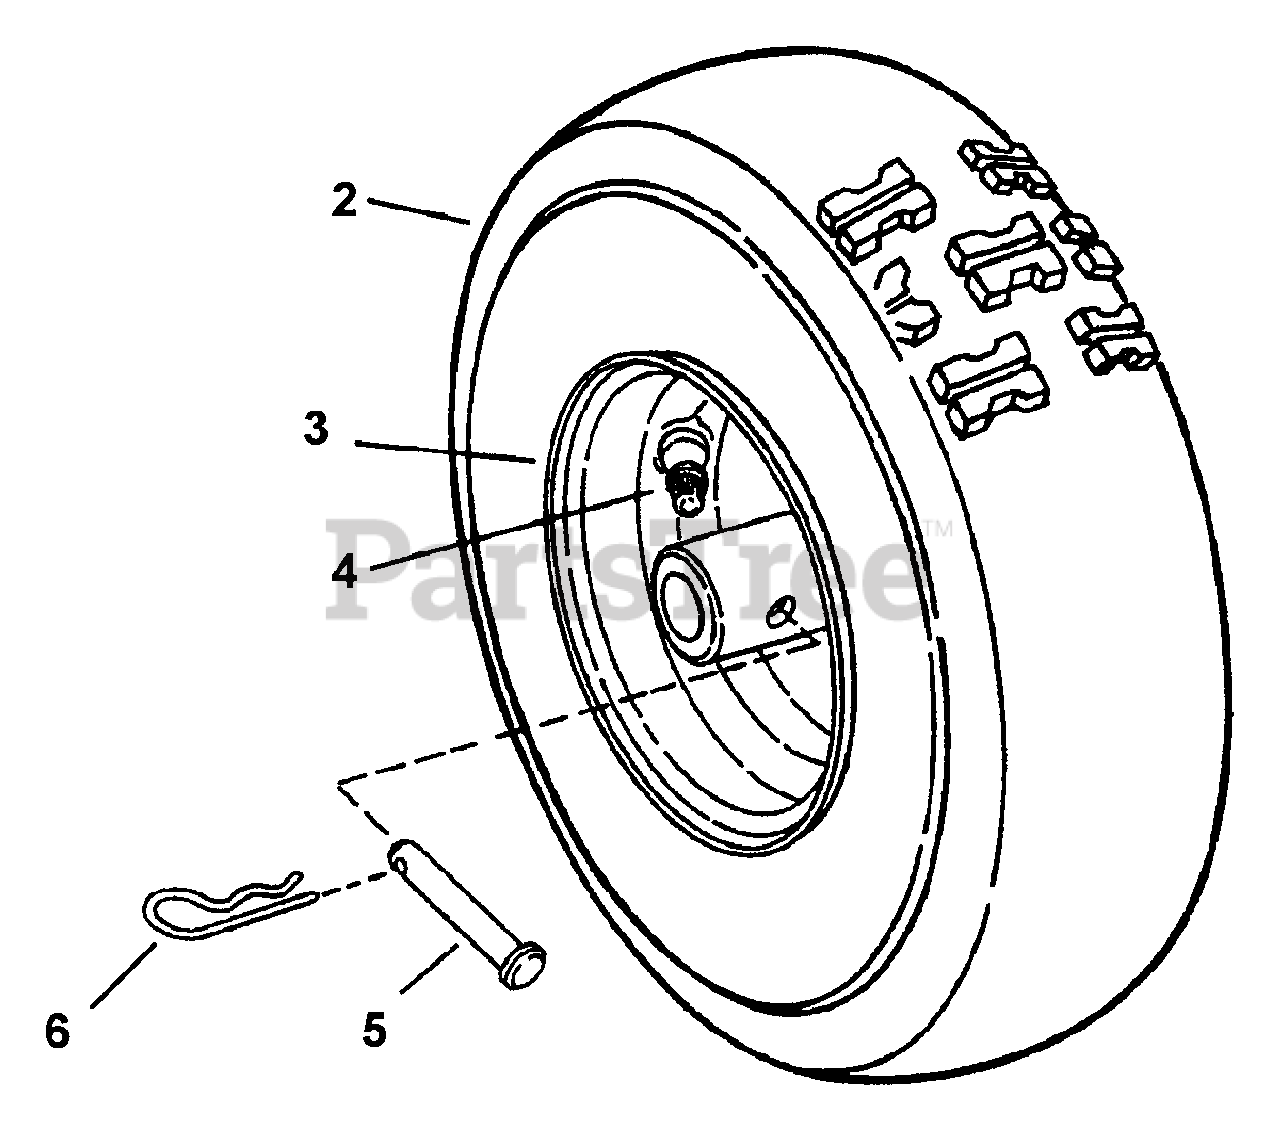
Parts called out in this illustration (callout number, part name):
2A	TIRE, 4.10 x 3.50 x 6
2B	TIRE, 4.10 x 3.50 x 6 (Kenda)
3A	RIM, 6 x 3.25
3B	RIM, 6 x 4
4	VALVE, Snap-In
5	PIN, 5/16 x 1-11/16" Clevis
6	PIN, 3/32 x 1-1/2" Hair
